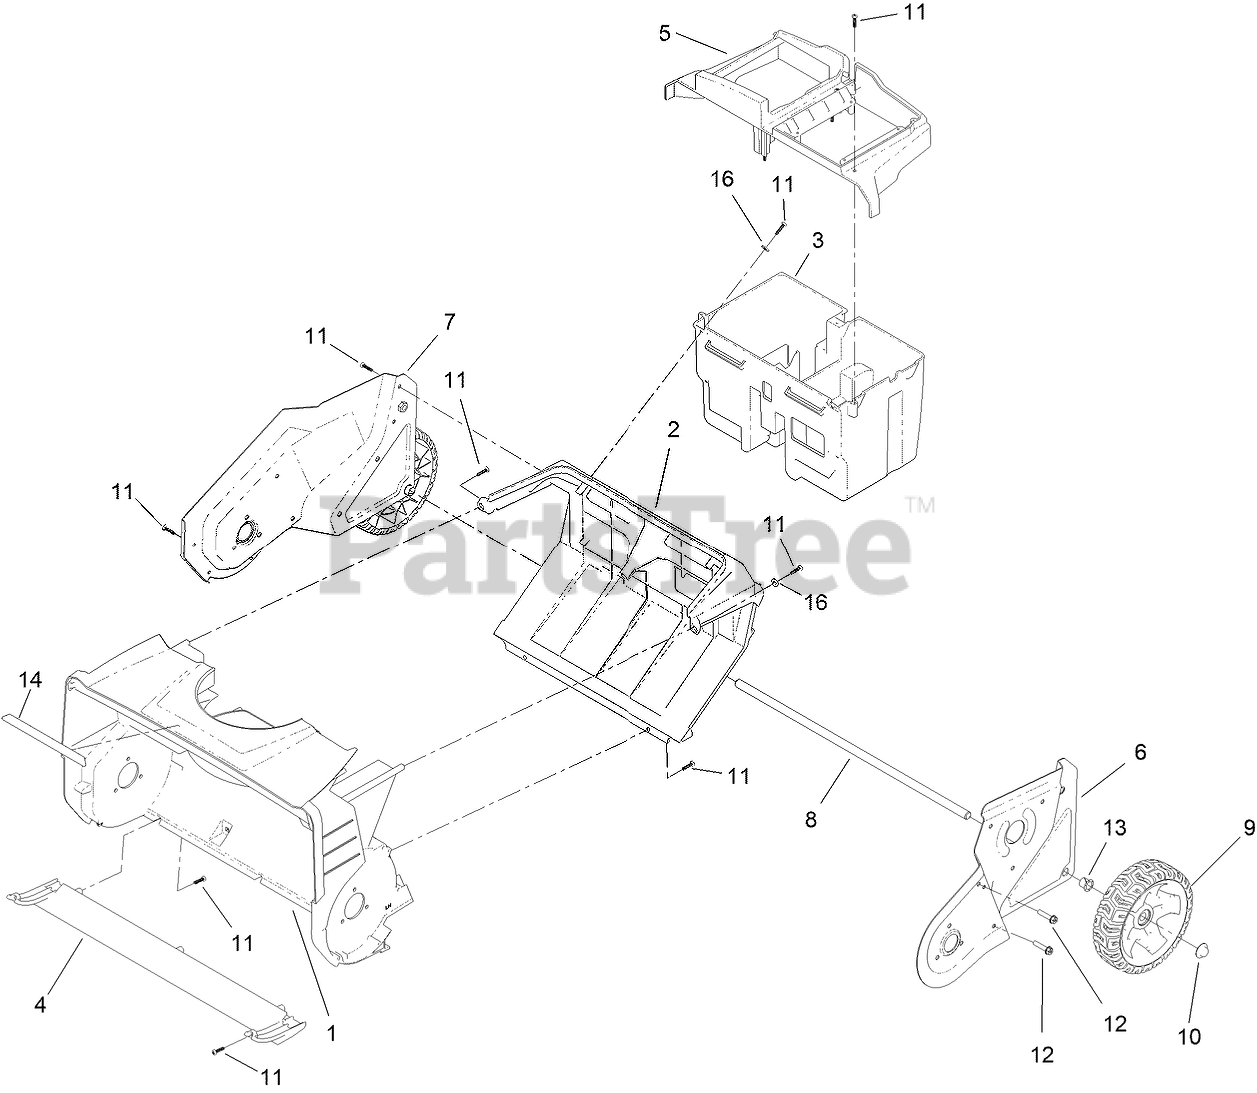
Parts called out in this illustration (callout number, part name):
1	HOUSING
2	BULKHEAD
3	CONTAINER-BATTERY
4	SCRAPER
5	SKIRT-CONTAINER, BATTERY
6	PLATE-FRAME ASSEMBLY, LH
7	PLATE-FRAME ASSEMBLY, RH
9	WHEEL ASM
10	NUT-PUSH
11	SCREW-PPH
12	SCREW-PLASTIC,HWH
13	BUSHING-NYLINER
14	DECAL-POWER EDGE
16	WASHER-FLAT
